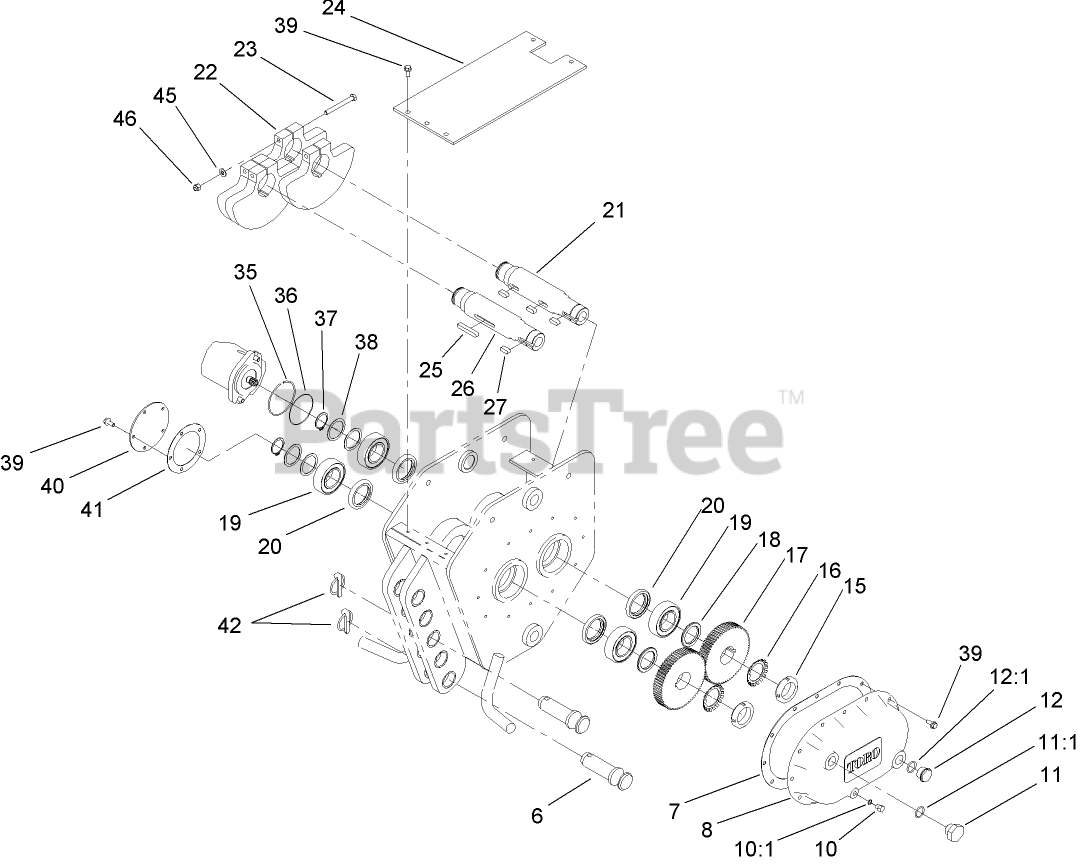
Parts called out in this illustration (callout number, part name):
6	PIN-BLADE
7	GASKET
10:1	O-RING
11	PLUG-HH
11:1	O-RING
12	GLASS-SIGHT
12:1	O-RING
16	RETAINER-NUT
18	SPACER
19	BEARING-ROLLER, SPHERICAL
20	SEAL-OIL
21	SHAFT-SPLINED
22	WEIGHT-COUNTER
23	SCREW-HH
24	PLATE-TOP
25	KEY-LONG
26	SHAFT
27	KEY-SHORT
35	RING-PILOT
36	O-RING
37	RING-RETAINING
38	WASHER-THRUST
39	SCREW-FLANGE
40	PLATE-COVER
41	GASKET
42	PIN-LYNCH
45	WASHER-FLAT
46	NUT-LOCK, NI
